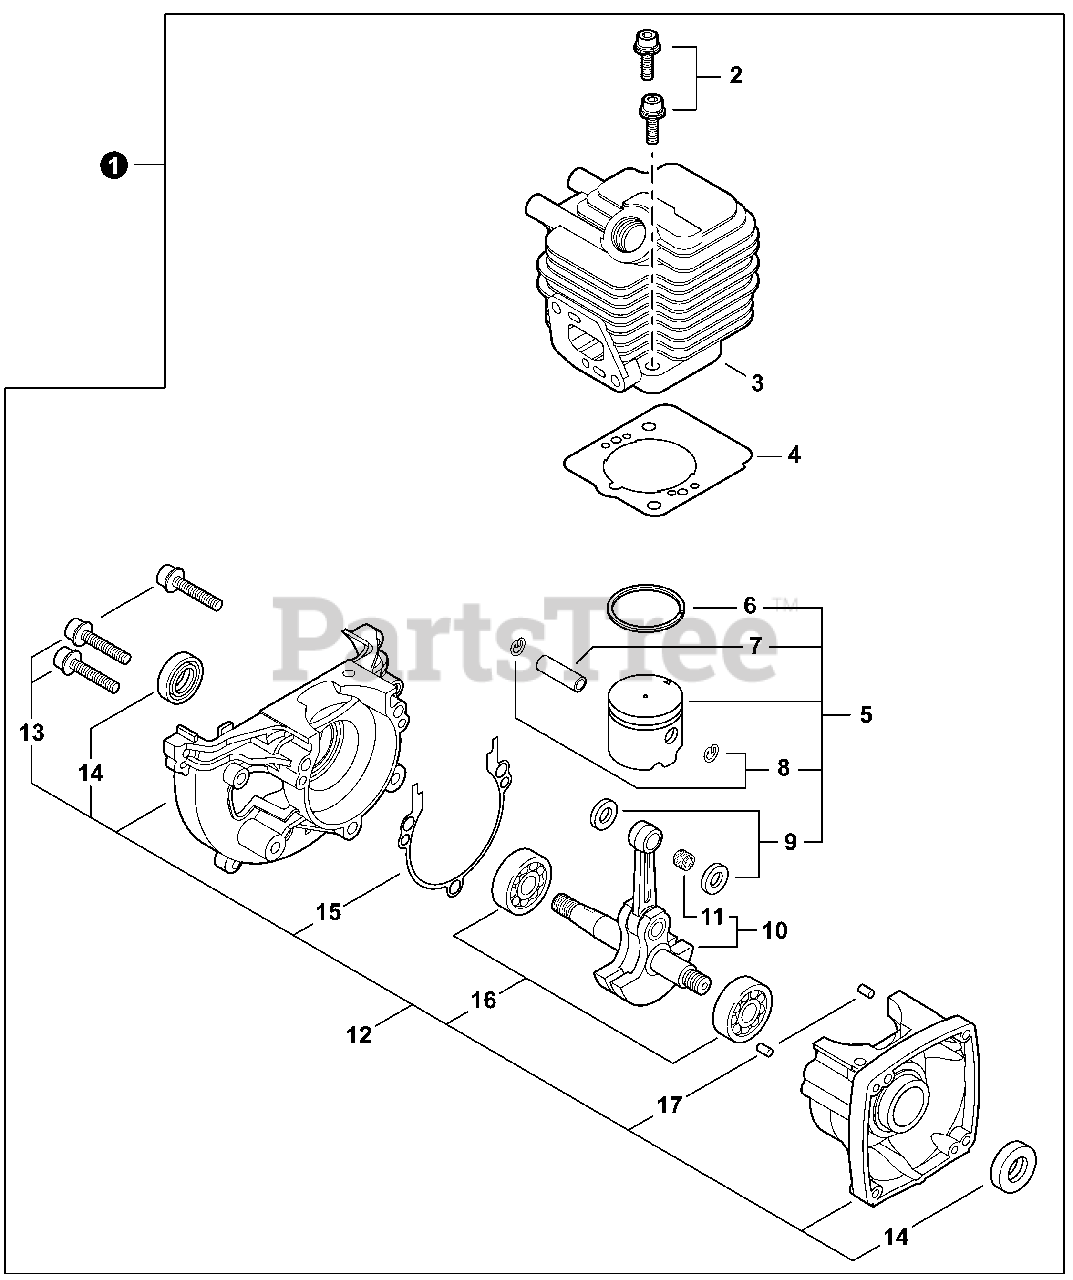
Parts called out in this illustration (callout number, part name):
1	SHORT BLOCK
2	BOLT 5×22
3	CYLINDER
4	GASKET, CYLINDER
5	PISTON KIT
6	RING, PISTON
7	PIN, PISTON 8
8	RING, SNAP
9	WASHER, THRUST
10	CRANKSHAFT ASSY
11	BEARING, NEEDLE 8
12	CRANKCASE KIT
13	BOLT 5×28
14	SEAL, OIL 12
15	GASKET, CRANKCASE
16	BEARING, BALL - 6201 C3
17	PIN, LOCATING 4×8
